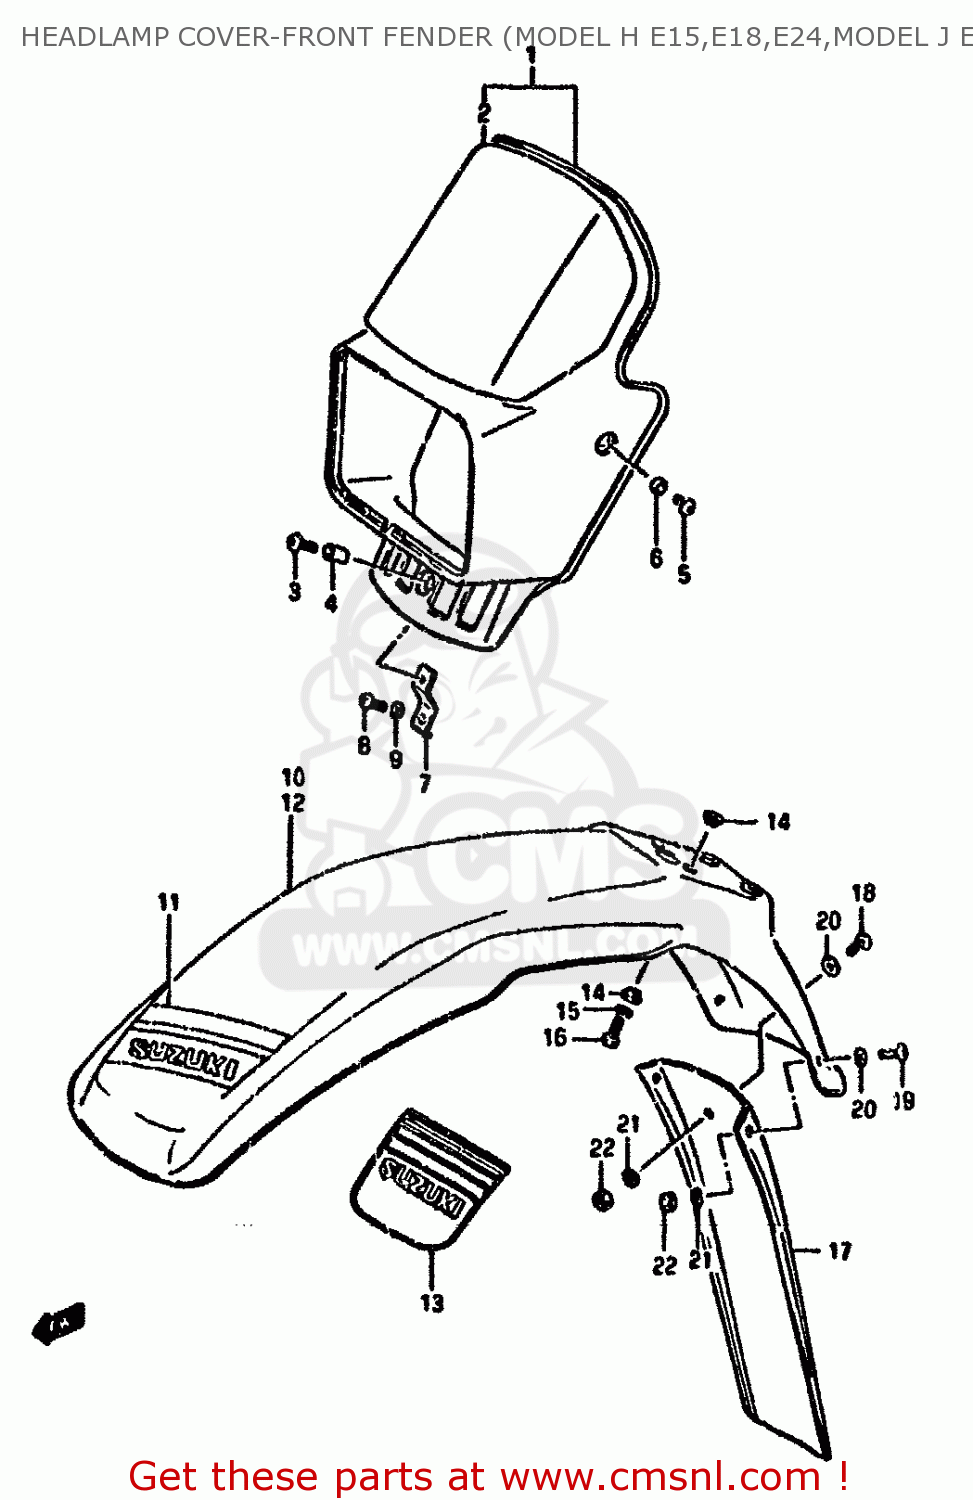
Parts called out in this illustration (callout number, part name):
1	COVER,HEADLAMP
2	TAPE SET
3	SCREW, CENTER
4	SPACER (6.1X8X12)
5	SCREW 6X12
6	SPACER (6.1X8X3.5)
7	BRACE,HEADLAMP HOUSING LWR
8	SCREW 6X12
9	WASHER,LOCK
10	FENDER,FRONT (BLUE)
11	TAPE SET
12	FENDER,FRONT (BLUE)
13	TAPE,FR FENDER
14	WASHER
15	WASHER,LOCK
16	BOLT
17	MUD FLAP
18	SCREW, CENTER
19	SCREW
20	WASHER (6.7X16X1.8)
21	WASHER,LOCK
22	NUT 6MM
